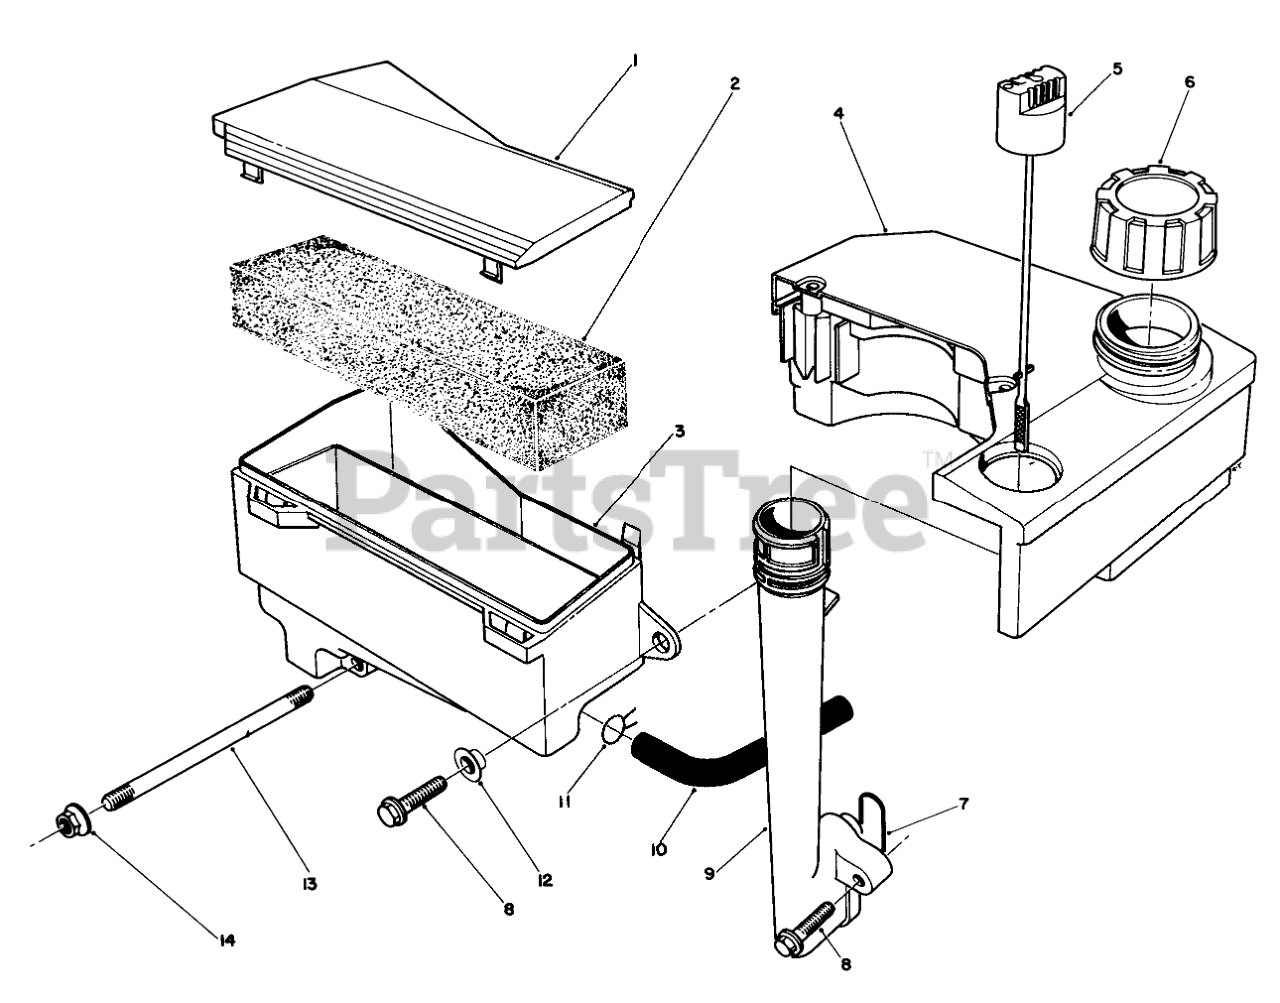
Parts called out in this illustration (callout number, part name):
1	AIR CLEANER CAP
3	Body-Air Cleaner
4	TANK ASM
5	Dipstick
6	GAS CAP ASM
7	O-RING
11	CLAMP F/W ENGINE
12	SPACER
13	Stud-Carburetor
